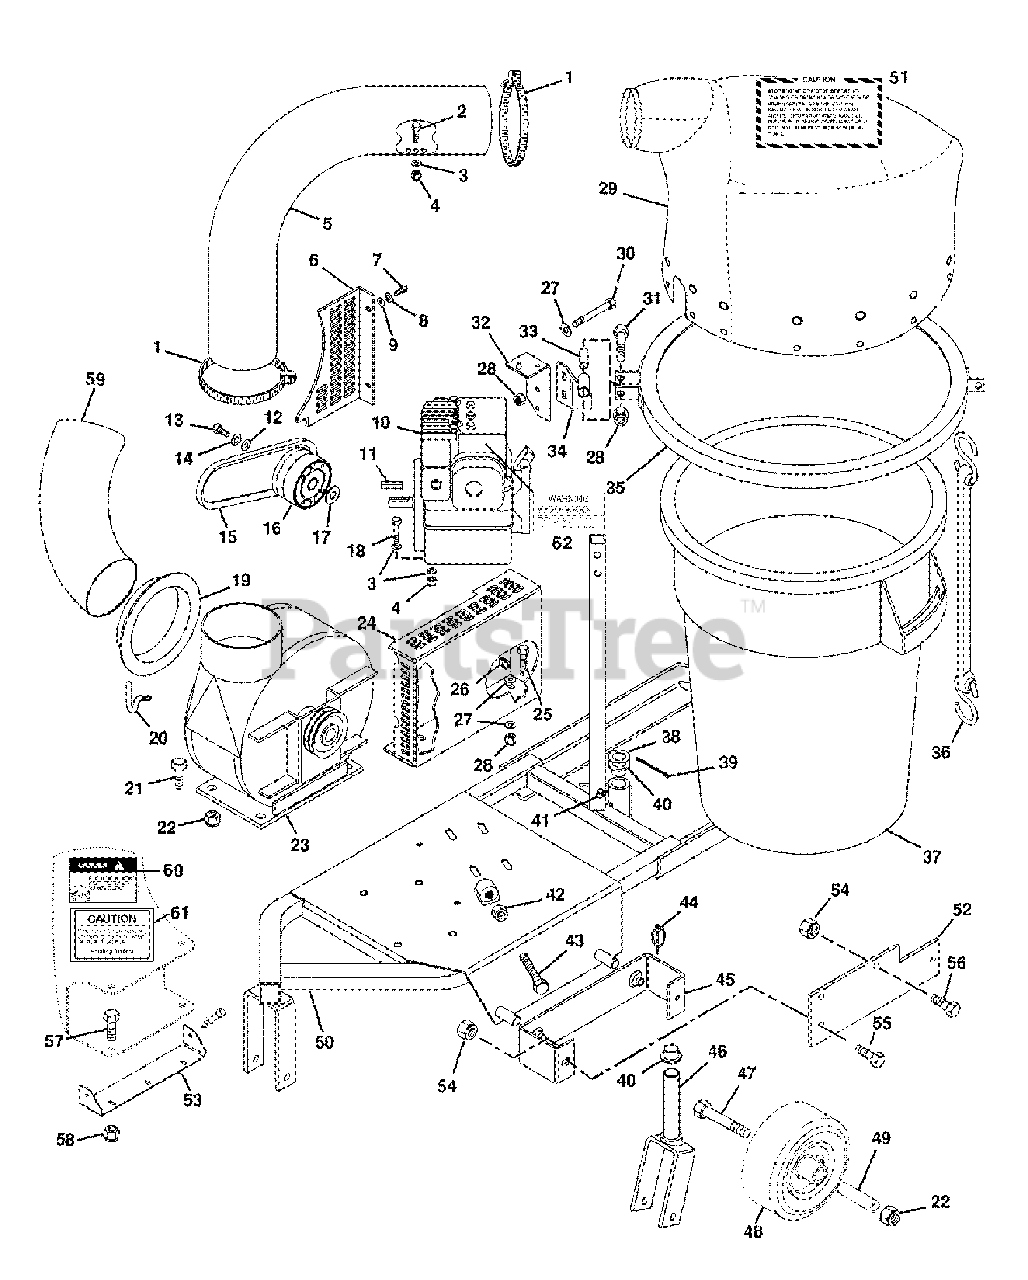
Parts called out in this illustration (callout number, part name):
2	Bolt-Hex .31-18 x 1.00 Grade 5
3	Washer-Flat .344 x .688 x .065
4	Nut-Locking-Center .31-18
5	Tube-Catcher
6	Cover-Guard
7	Bolt-Hex .25-20 x .75 Grade 5
8	Washer-Locking .25 x .062
9	Washer-Flat-Steel .281 x .620 x .065
10	Engine, 5.5HP Kawasaki
11	Key-Hub .187 x 1.500
12	Washer-Flat-Steel .38 x .875 x .083
13	Bolt-Hex .31-24 x .75 Grade 5
14	Washer-Locking .31 x .078
17	Race-Bearing-Thrust .060
18	Bolt-Hex .31-18 x 1.75 Grade 5
19	Weldment, Blower Adapter
20	Clamp-Screw
21	Bolt-Hex .50-13 x 1.25 Grade 5
22	Nut-Locking-Center .50-13
23	Assembly, PM-310 Blower
25	Bolt-Hex .38-16 x .75 Grade 5
26	Nut-Retainer
27	Washer-Flat .406 x .812 x .065
28	Nut-Locking-Center .38-16
29	Cover-Grass Catcher
30	Bolt-Hex .38-16 x 2.50 Grade 5
31	Bolt-Hex .38-16 x 2.00
32	Bracket-Tube
33	Bushing .385 x .625 x 1.00
34	Weldment-Pivot Bracket
35	Weldment-Ring
36	Strap-Hold Down
37	Can-Grass
38	Race-Bearing-Thrust
39	Pin-Center .12 x 1.25
40	Bearing-Flanged
41	Fitting-Lube 90 Degree
42	Nut-Hex .38-16
43	Bolt-Hex Spec. .38-16 x 3.00
44	Pin-Klik
45	Weldment-Catcher Mount
46	Weldment-Castor
47	Bolt-Hex .50-13 x 5.50
48	Wheel-Wing Gauge
49	Bushing-Axle
50	Weldment-Catcher
52	Plate, Bagger Adapter
53	Bracket, Boot Mounting
54	Nut-Locking-Center .62-11
55	Bolt-Hex .62-11 x 1.50 Grade 5
56	Bolt-Hex .62-11 x 2.00 Grade 5
57	Bolt-Hex .38-16 x 1.00 Grade 5
58	Nut-Locking-Nylon .38-16
59	Hose, Blower 8" x 40
